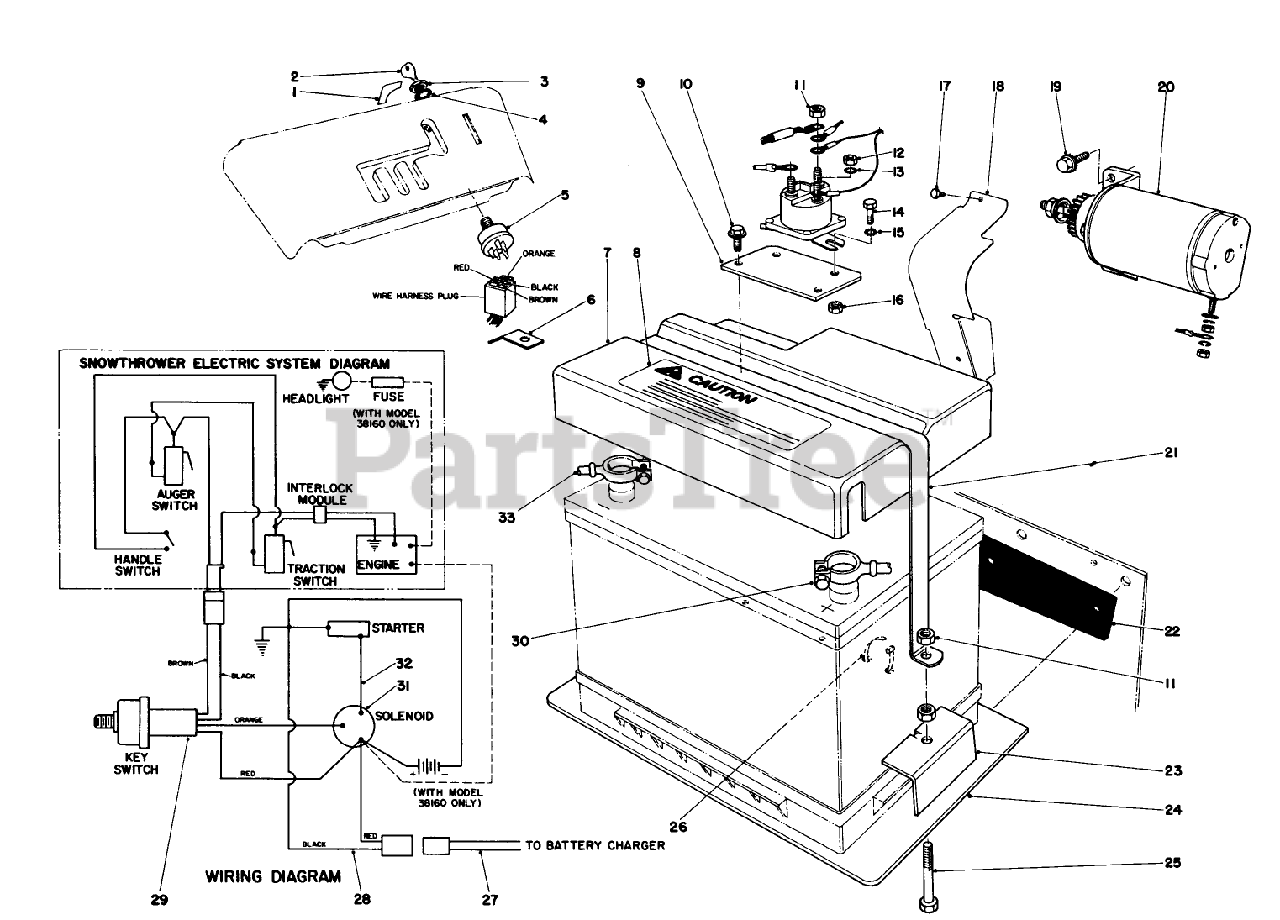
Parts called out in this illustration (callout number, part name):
3	NUT-HH
4	WASHER-LOCK
10	SCREW-HWH
11	NUT-HEX
12	NUT-HEX
13	WASHER-LOCK, INT
14	SCREW-HH
15	WASHER-LOCK/EXT
16	NUT-LOCK, NI
18	BRIGGS 280265
19	5/16-18X3/4 HX HD SEM
20	Starter Motor Pinion Assy.
25	SCREW-HH
26	TIE-CABLE
27	MALE WIRE ASM
30	BATT-SOLENOID CABLE
31	SOLENOID
